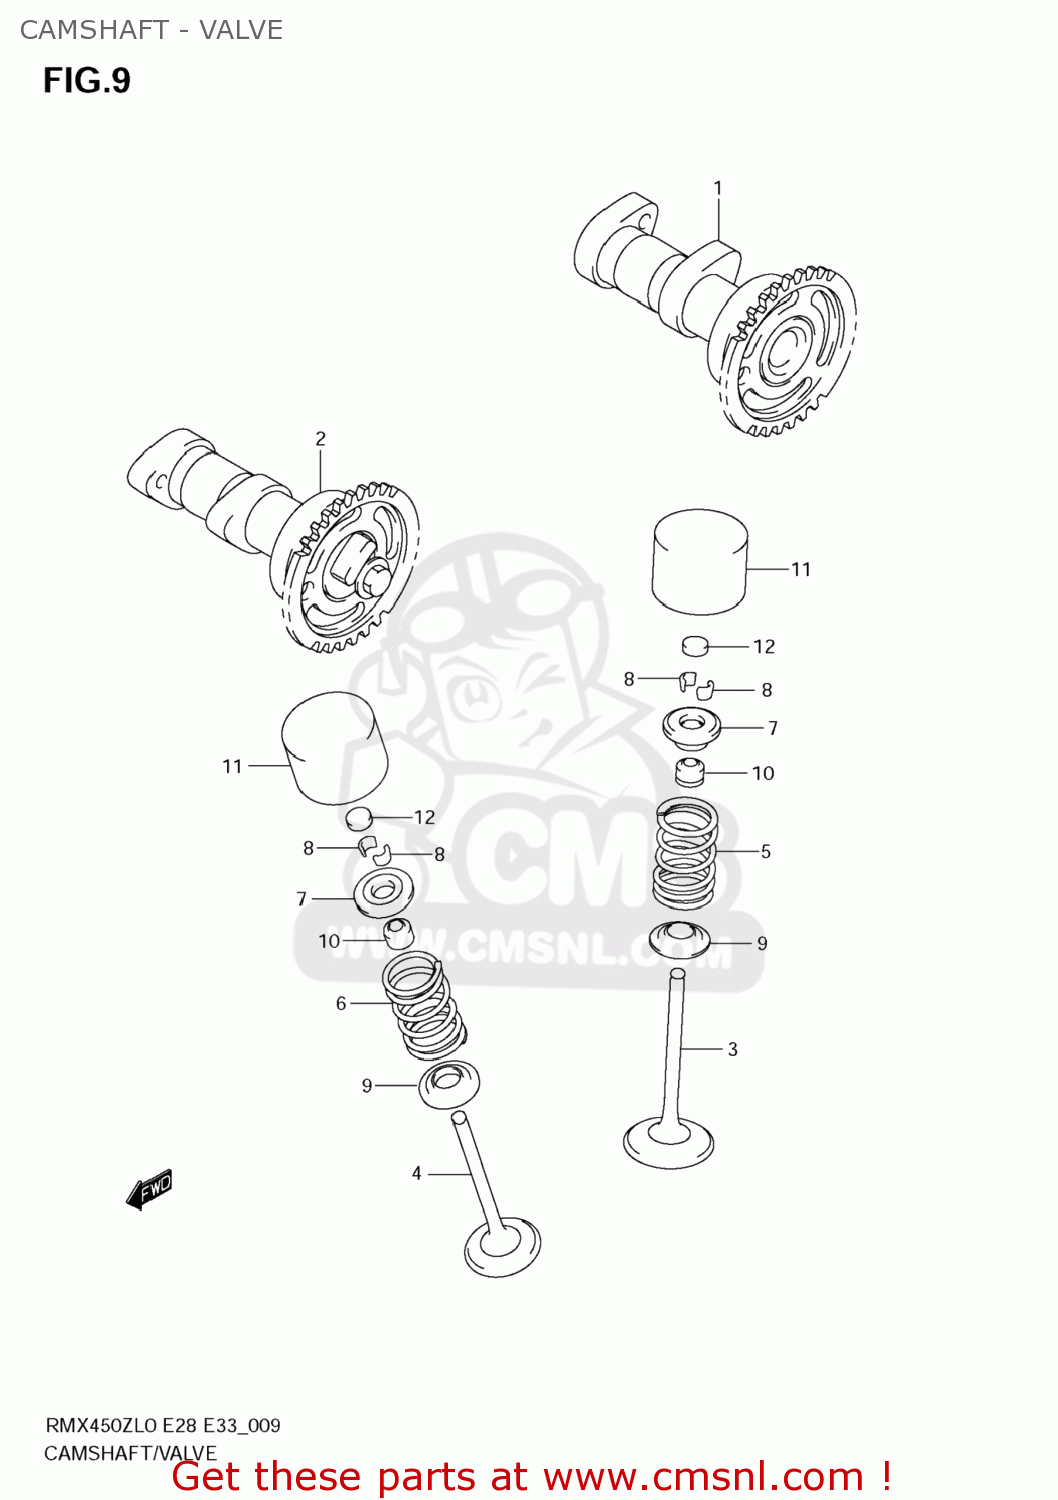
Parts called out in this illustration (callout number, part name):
1	CAMSHAFT,INTAKE
2	CAMSHAFT,EXHAUST
3	VALVE,INTAKE
4	VALVE,EXHAUST
5	SPRING,VALVE
6	SPRING,VALVE
7	RETAINER,VALVE SPRING
8	COTTER,VALVE
9	SEAT,VALVE SPRING
10	SEAL,OIL(5.5X11X8.2)
11	TAPPET
12	SHIM,TAPPET
13	SHIM SET,TAPPET
14	CASE,TAPPET SHIM
